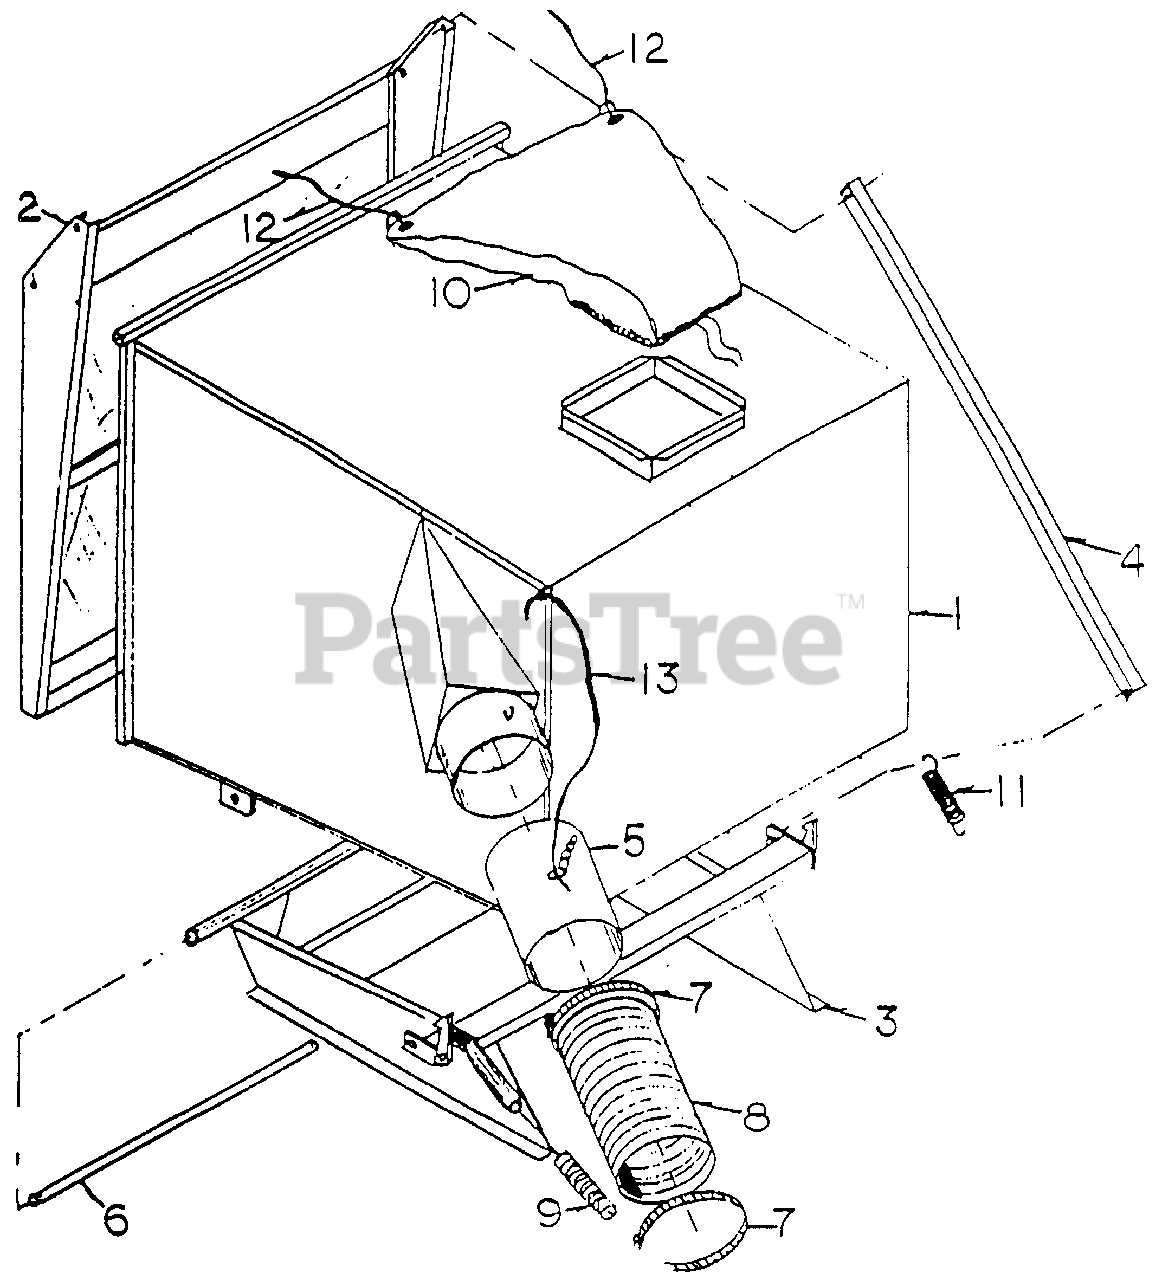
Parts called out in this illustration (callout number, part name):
1	GRASS BOX
3	DOOR MOUNT
4	DOOR LINKACE
5	MALE llJBE
8	HOSE
9	HANDLE GRIP
12	BAG ROPE
13	MALE TUBE ROPE
